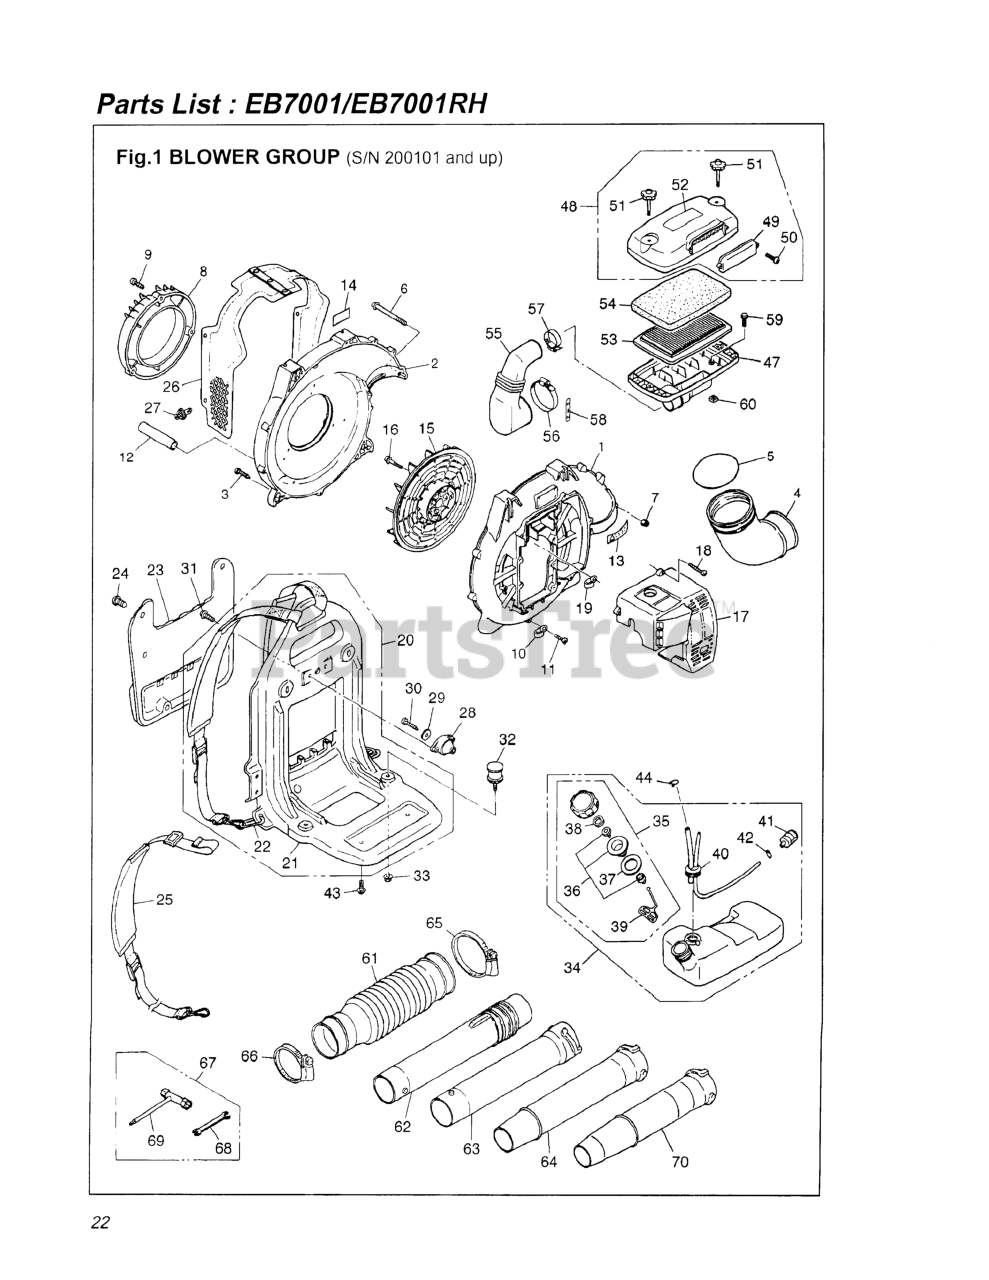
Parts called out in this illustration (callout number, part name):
1	CASE, VOLUTE
2	848-L5C-55B3
3	SCREW, M5 X 25
4	ELBOW
5	O-RING
6	SCREW, M5 X 70
7	NUT (B)
8	COVER, INLET
9	SCREW, M5 X 25
10	CLAMP
12	TUBE (RPLS. 07270-01507)
13	LABEL, CAUTION (RPLS -31910)
14	LABEL, NET
15	FAN
16	BOLT (RPLS 3405-12211)
17	COVER, ENGINE (RPLS -31611)
18	SCREW, M5 X 25
19	CLAMP
20	T4012-32002 (REPLACES -32000)
21	FRAME COMP. (RPLS -32100)
22	RING (REPLACES -21120)
23	PAD
24	CLIP (RPLS 3490-21320)
25	BAND ASSY (RPLS 2750- )
26	NET COMPLETE
27	CLIP
28	DAMPER, UPPER
29	WASHER
30	SCREW
31	BOLT, M5 X 16 (RPLS -32540)
32	DAMPER, LOWER
33	NUT, M6
34	TANK ASSY (RPLS. -85100)
35	CAP ASSY (RPLS -85201)
36	HOLDER (REPLACES -85230)
37	PACKING
38	FILTER
39	STOPPER
40	PIPE COMPLETE
41	FILTER ASSY
42	CLIP (REPLACES 2841-31280)
43	SCREW, M5 x 12
44	CLIP
48	COVER ASSEMBLY
49	COVER
50	SCREW, M5 X 25
51	BOLT, KNOB
52	LABEL, CLEANER
53	ELEMENT (PAPER)
55	HOSE
56	BAND
57	BAND
58	LABEL, CHOKE
60	NUT
61	HOSE
62	SWIVEL-JOINT (REPLACES -51200)
63	PIPE, STRAIGHT
64	PIPE, END
65	CLAMP
66	CLAMP (RPLS 3050-13230)
67	TOOL SET
68	SPANNER, 8 X 10 (RPLS 2540- )
69	WRENCH, SOCKET
70	KIT, NOZZLE (USE 2756-51221)
